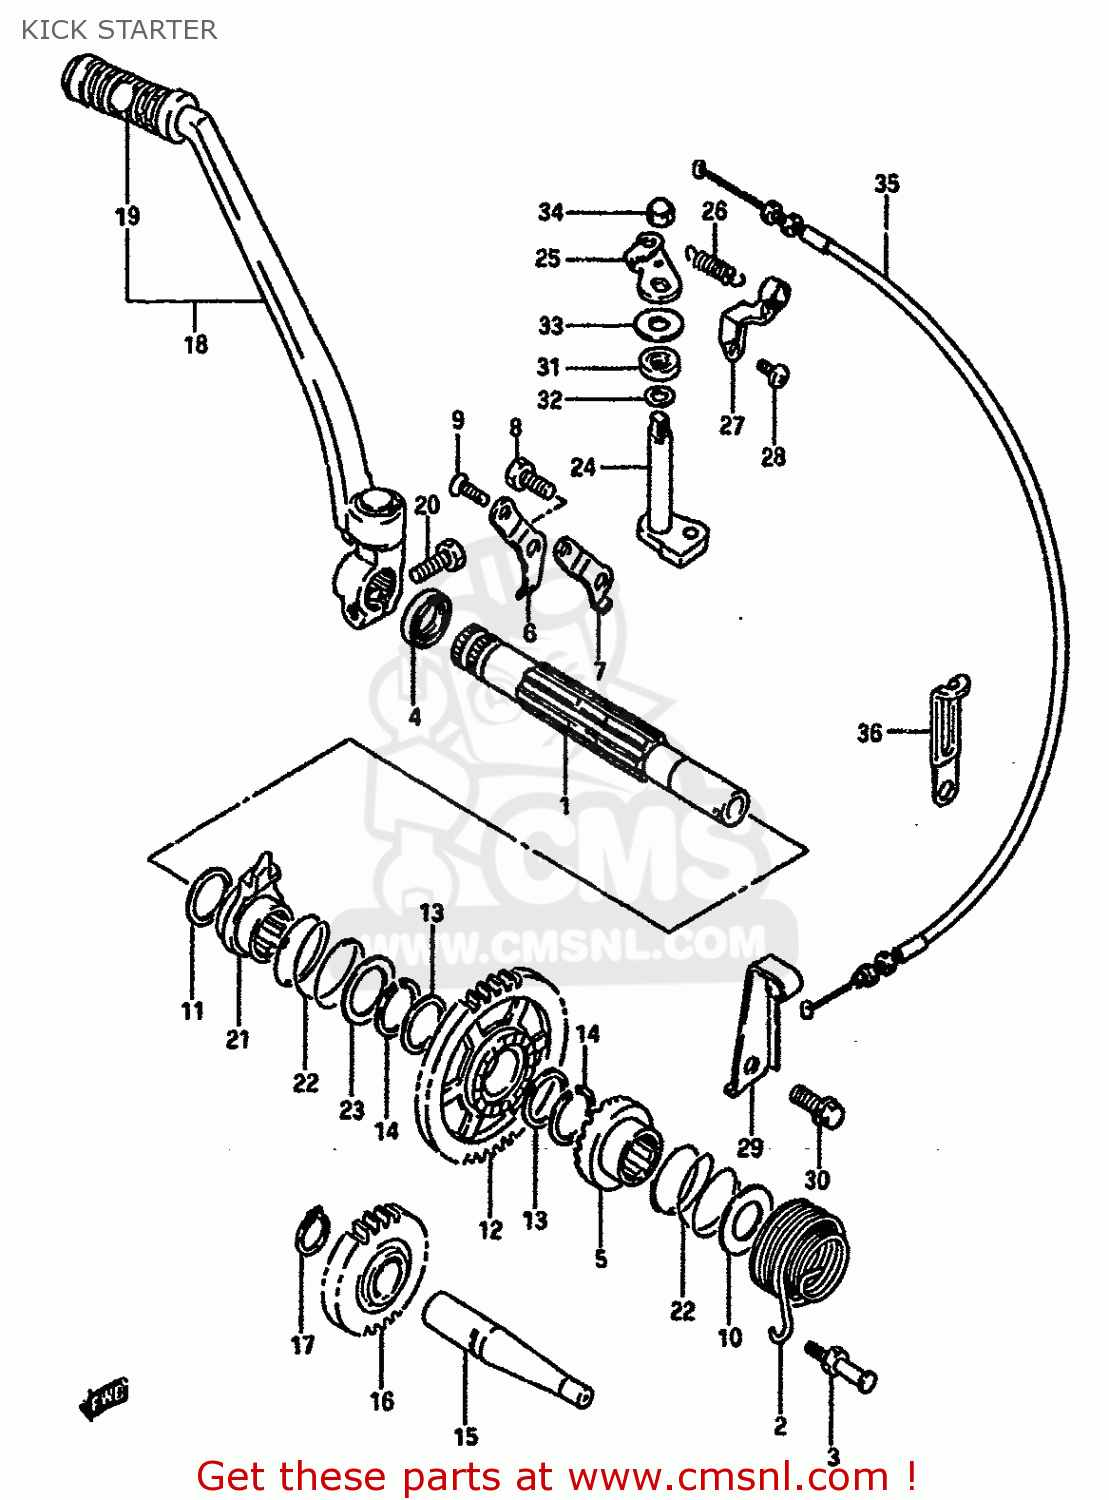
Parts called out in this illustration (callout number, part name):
1	SHAFT,KICK STARTER
2	SPRING
3	BOLT,KICK SHAFT SPRING
4	SEAL,OIL(20X27X6)
5	STARTER,KICK
6	GUIDE,KICK STARTER
7	STOPPER,KICK STARTER
8	BOLT,8X1.25X2
9	SCREW
10	WASHER
11	WASHER,THRUST
12	GEAR,KICK STARTER DRIVE
13	SHIM
14	CIRCLIP
15	SHAFT,KICK STARTER IDLE
16	GEAR,KICK STARTER IDLE
17	CIRCLIP
18	LEVER ASSEMBLY,KICK STARTER
19	RUBBER,KICK STARTER PEDAL
20	BOLT 8X25
21	CAM,DECOMPRESSION
22	SPRING
23	WASHER
24	SHAFT,DECOMP CAM FOLLOWER
25	ARM,DECOMPRESSION SHAFT
26	SPRING
27	HOLDER,DECOMPRESSION CABLE NO
28	SCREW
29	HOLDER,DECOMP CABLE NO.2
30	BOLT, LOWER
31	OIL SEAL
32	WASHER
33	WASHER(10.5X24X1)
34	NUT,M8X1.25X12
35	CABLE,KICK STARTER DECOMP
36	CLAMP L:35
